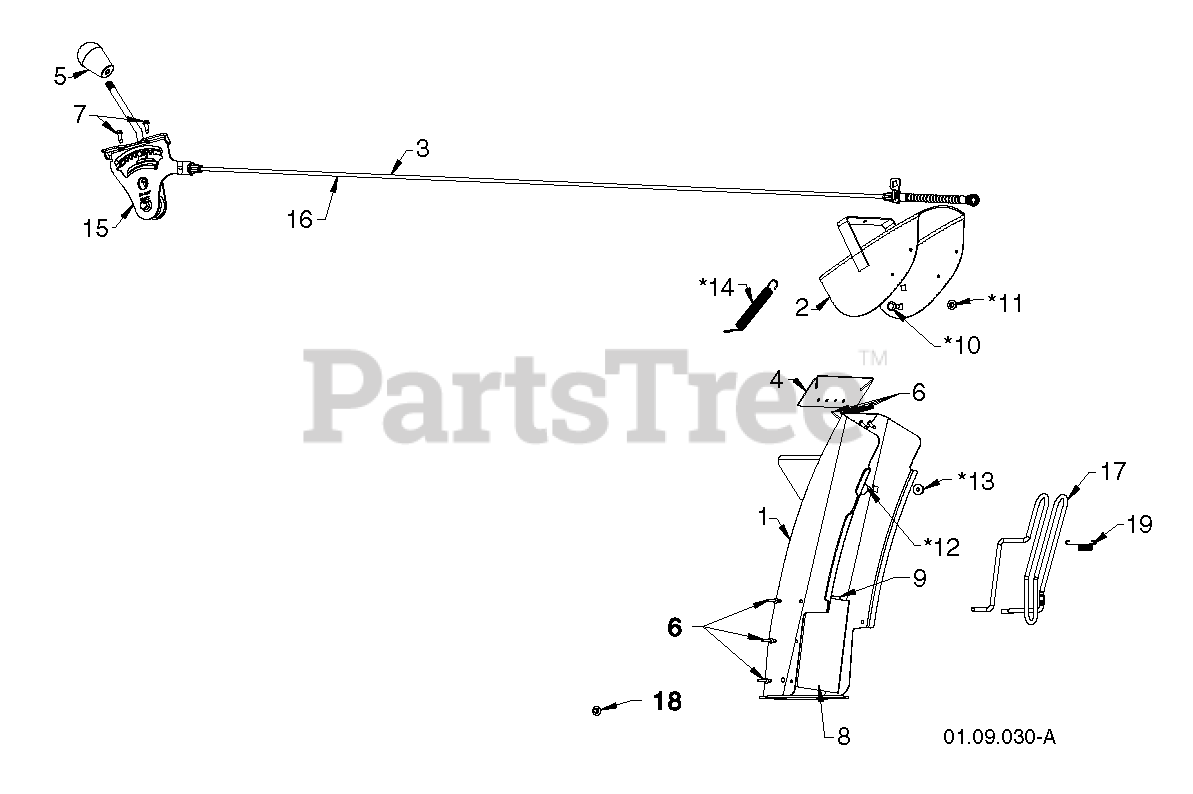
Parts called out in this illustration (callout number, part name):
1	RP_CHUTE.WELDMENT.SNOW.ORANGE
2	DEFLECTOR.WELDMENT.PNT.ORANGE
3	RP CRTL.ASM.DEFLECTOR.BLACK.SN
4	SEAL.DEFLECTOR
5	KNOB.OVERMOLD.DS.HUSQVARNA/BLK
6	RIVET BLIND
8	SHIELD.SNOW.CHUTE
9	STRAP.SHEILD.RETAINER
10	BOLT, SHOULDER
11	NUT.HEX.FLANGE.1/4
12	BOLT
13	NUT.LOCK.5/16-18
14	SPRING.DEFLECTOR.REM.CHUTE
15	RP CNTRL.HEAD.ASSEM.DEFLECTOR
16	CABLE.DEFLECTOR.SNOW
17	ROD.GUARD.CHUTE (2 2)
18	NUT
19	SPRING.CHUTE.GUARD
